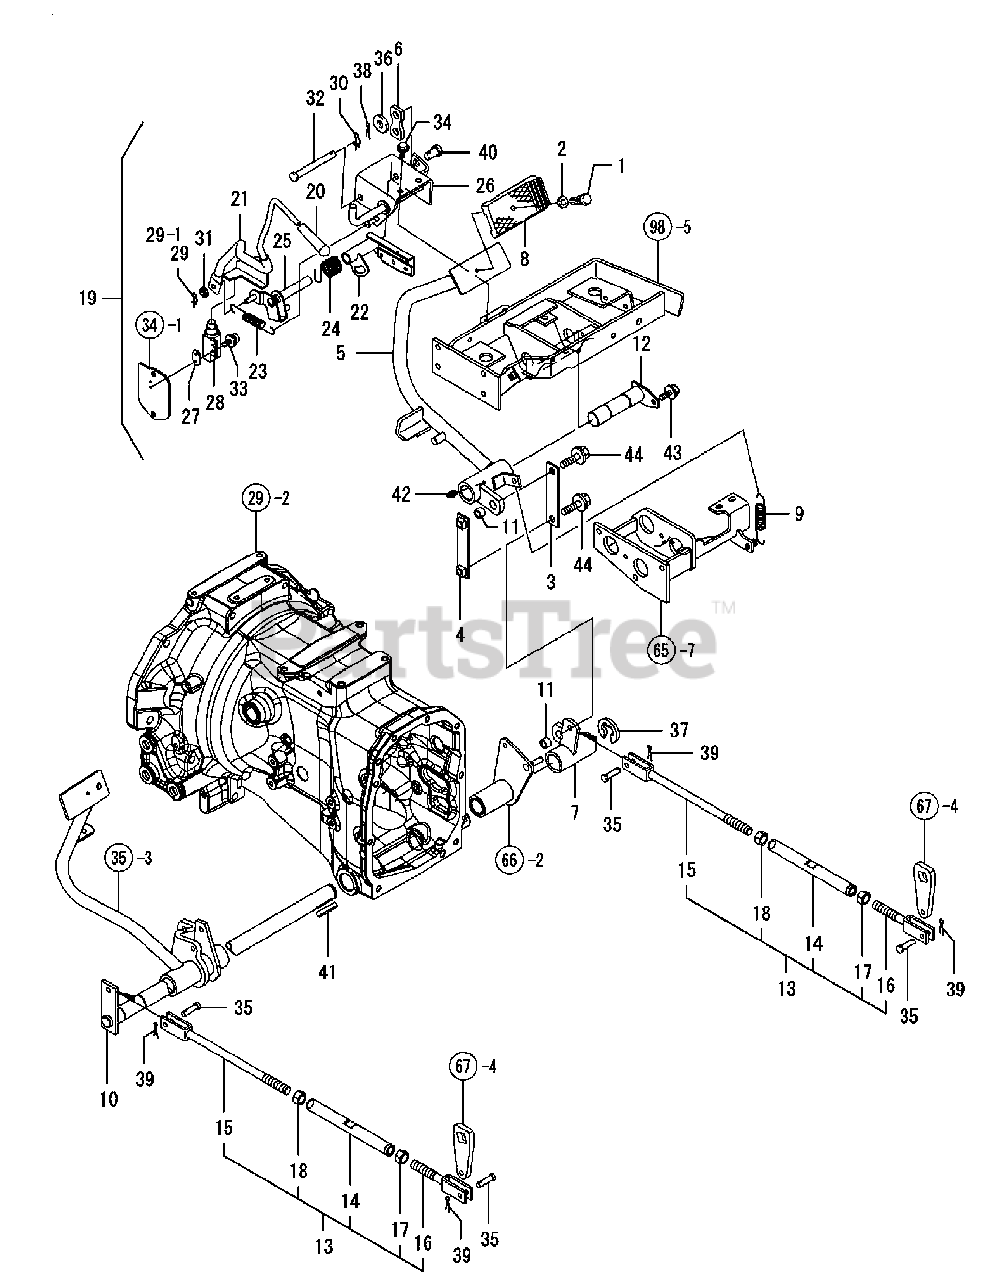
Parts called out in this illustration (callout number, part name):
1	RIVET, PEDAL HEAD
4	LINKAGE, BRAKE
6	PLATE, CRUISE RELEASE
8	COVER, PEDAL HEAD
9	SPRING, RETURN
10	SHAFT, BRAKE PEDAL
11	COLLAR, 15X10X10
13	ROD, BRAKE CMP
14	TURNBUCKLE, BRAKE
16	ROD, BRAKE LH SCREW
19	PARKING-BRAKE KIT
21	ROD, PARKING CMP
22	LOCK LEVER, BRAKE
25	LEVER, B PARKING
26	SUPPORT, P BRAKE CMP
27	WASHER, SWITCH
28	STOP LAMP SW, DELTA
29	PIN 8, SNAP
29-1	COTTR PIN 2.5 X 30
31	WASHER 8, POLISHED
34	BOLT M 8X 16 PLATED
36	WASHER 12, POLISHED
38	COTTER PIN 2.5X30
39	COTTER PIN 2.5X30
40	PIN, FLAT HEAD 12X16
42	NIPPLE M6F, GREASE
43	BOLT M 8X 16 PLATED
44	BOLT M10X 25 PLATED
